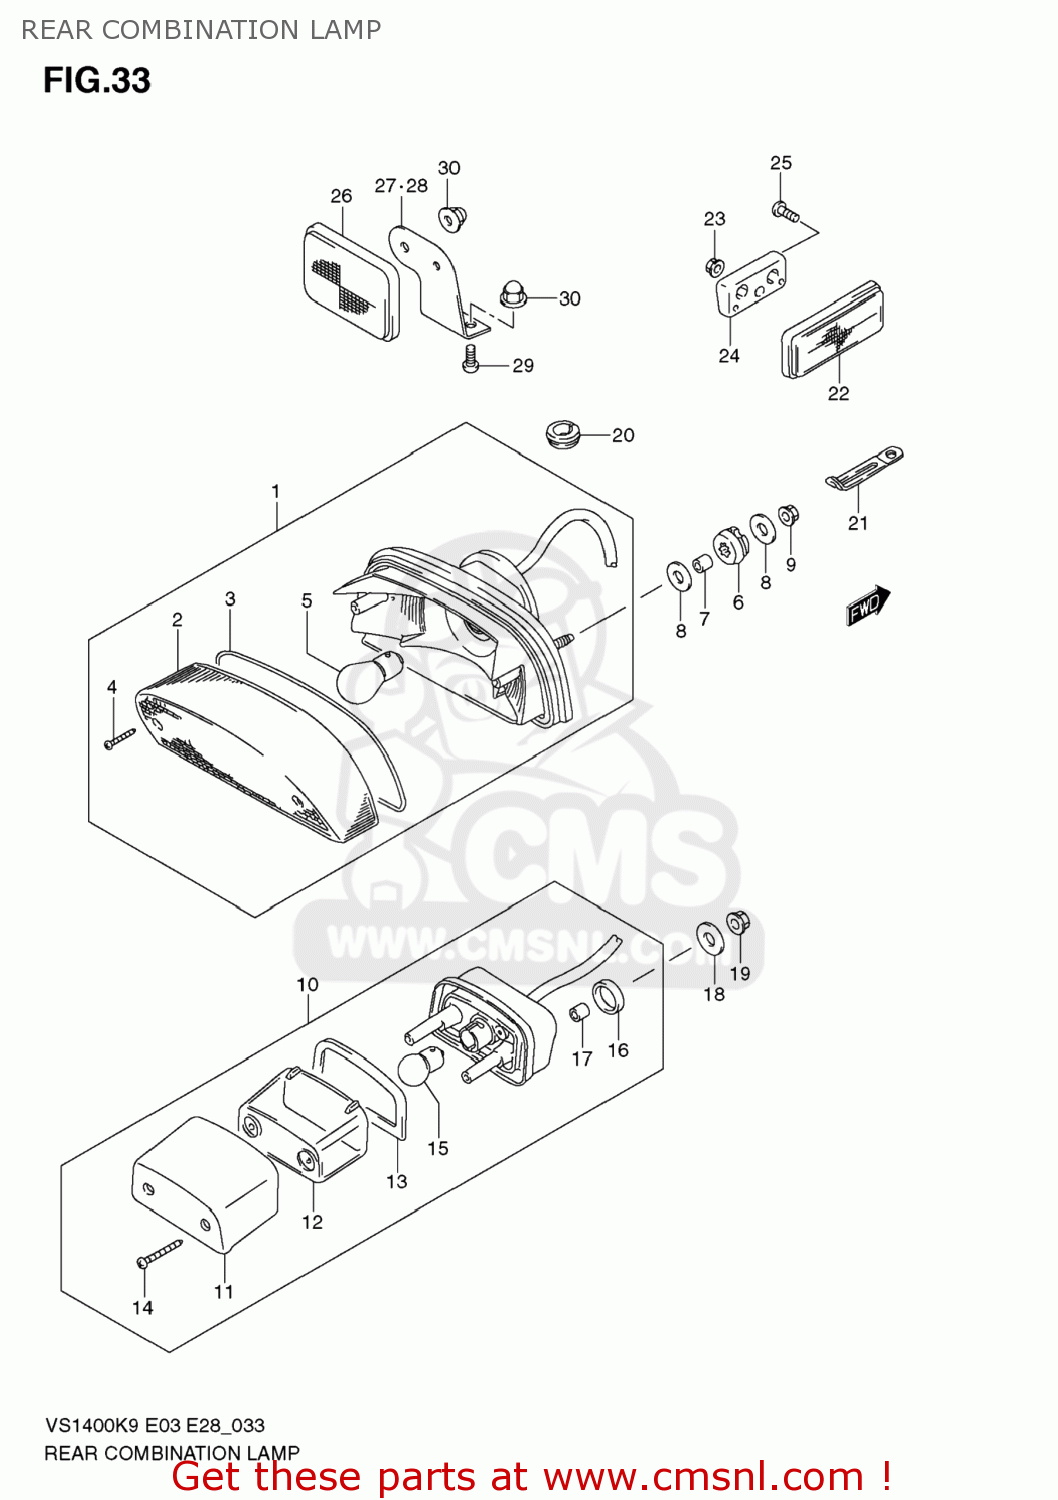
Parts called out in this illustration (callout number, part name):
1	LAMP ASSY,RR COMBINATION
2	LENS
3	GASKET (NAS)
4	SCREW
5	BULB(12V27/8W)
6	CUSHION
7	SPACER(6.5X9X10.5)
8	WASHER(6.5X20X1.2)
9	NUT
10	LAMP ASSY,LICENSE
11	COVER,LICENSE LAMP
12	LENS,LICENSE LAMP
13	GASKET,LICENSE LAMP (NAS)
14	SCREW
15	BULB(12V7.5W)
16	CUSHION
17	SPACER
18	WASHER(6.5X20X1.2)
19	NUT
20	GROMMET
21	CLAMP(L:45)
22	REFLECTOR ASSY,RR
23	NUT
24	SPACER,RR SIDE REFLECTOR
25	SCREW
26	REFLECTOR ASSY,RR
27	BRACKET,RR RR
28	BRACKET,RR RR,L
29	SCREW
30	NUT
